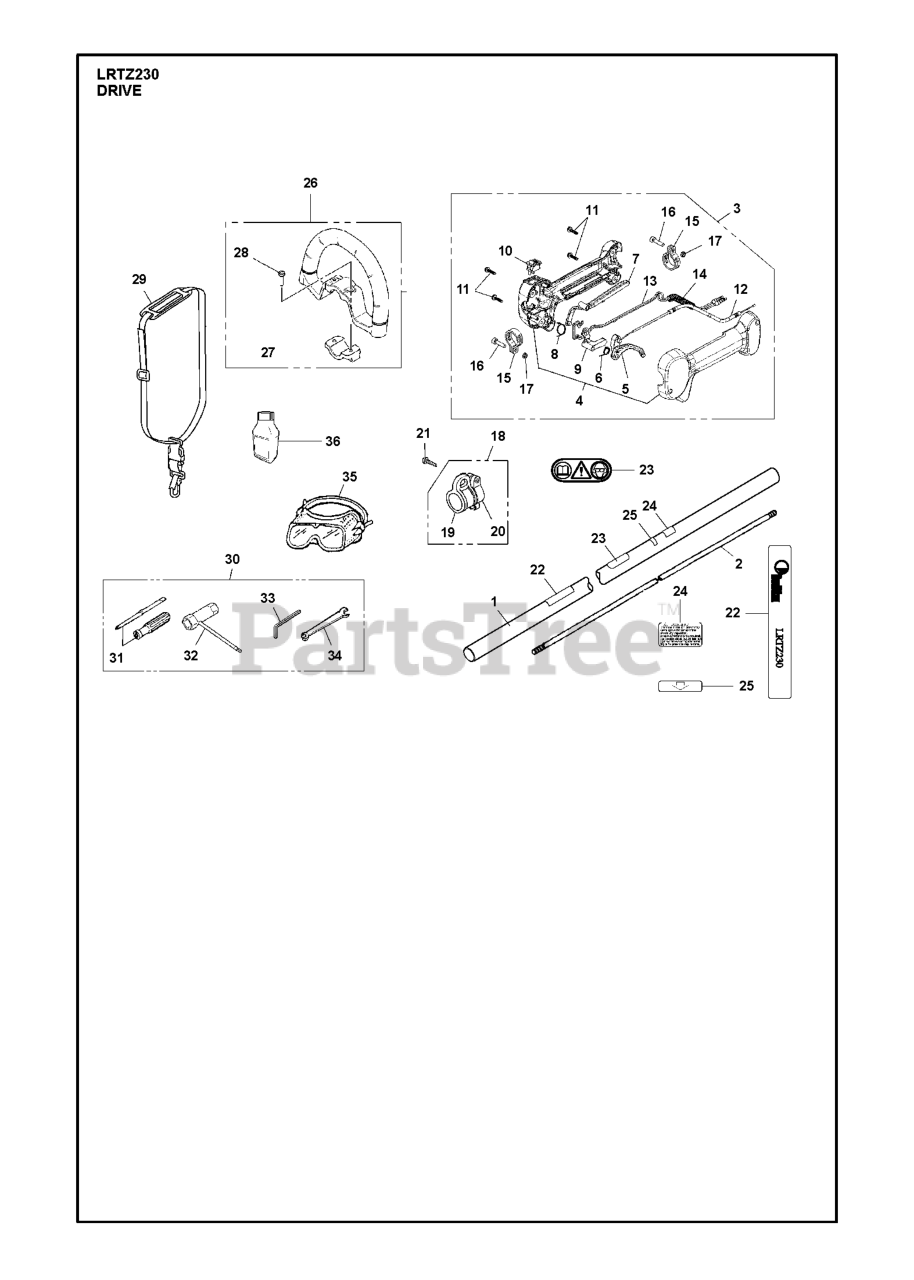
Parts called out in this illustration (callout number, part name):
1	TUBE
2	DRIVESHAFT 525L
3	ASSY THROTTLE
4	GRIP HALF SET
5	LEVER, THROTTLE
6	SPRING, THROTTLE
7	LEVER, SAFETY
9	LEVER JOINT
10	STOP SWITCH NM_09091801
13	CORD - C
17	NUT
18	HANGER COMP
23	LABEL (CAUTION)
24	DECAL SPARK ARRESTOR WARNING
26	HANDLE LOOP
27	CLAMP HANDLE
29	STRAP ASSY
30	TOOL-SET
35	GOGGLExxx (RPLS
36	OIL 2 CYCLE ENGINE OIL 2.
